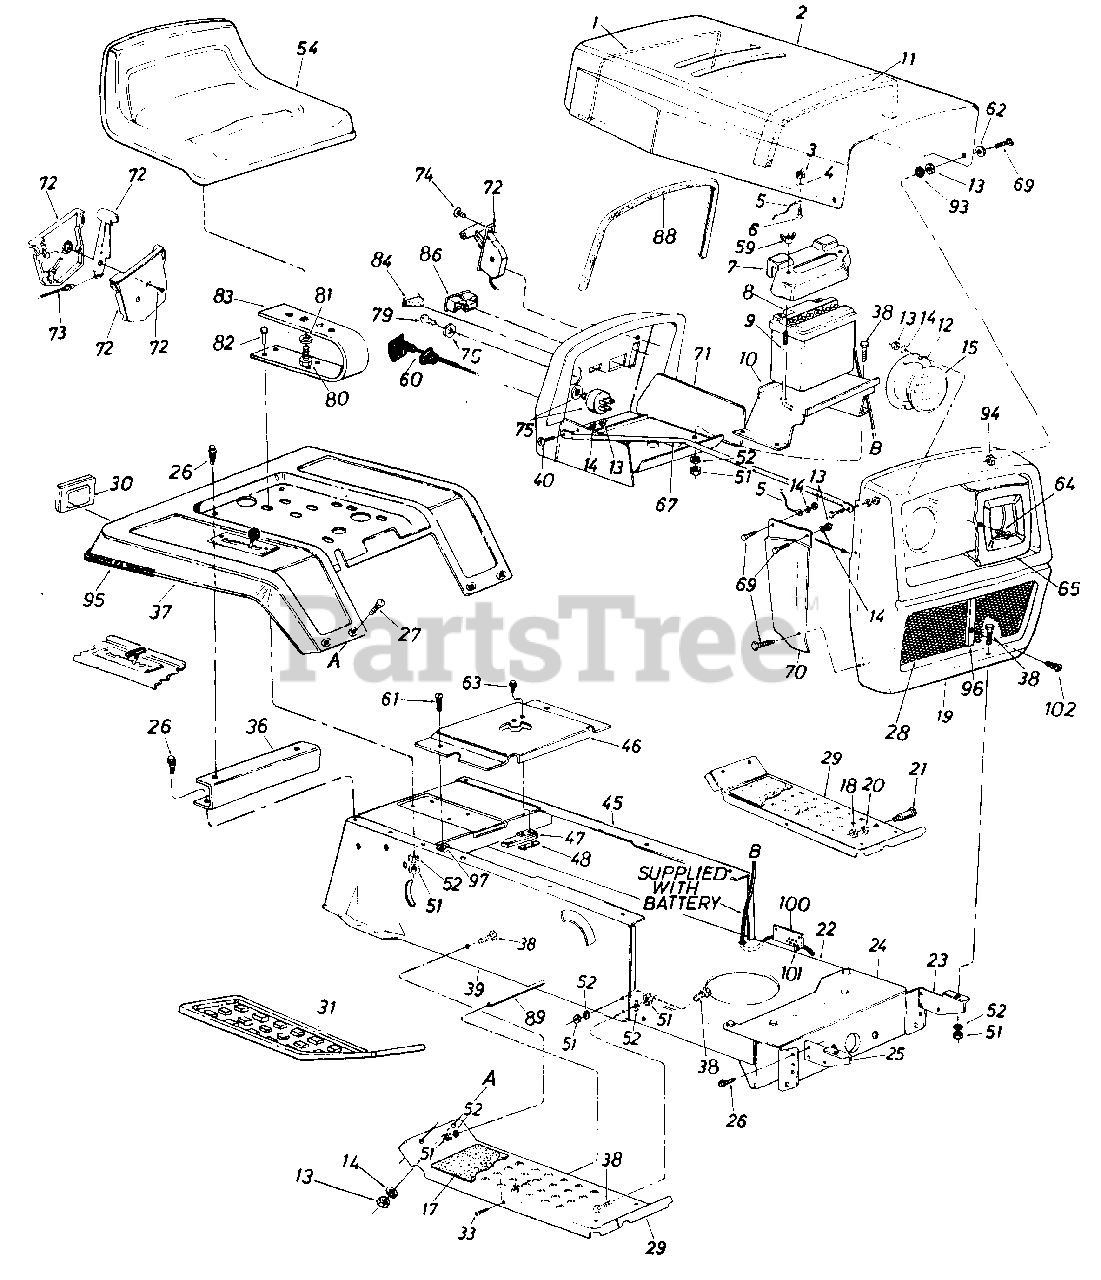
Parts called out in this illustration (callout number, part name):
2	Hood
3	Hex Sems Nut #10-24 Thd*
4	Push Mount Tie
5	Hood Stop 7" Lg.
6	Truss Hd. Scr. #10-24 x 1/2"*
7	Battery Cover
8	12 Volt Battery
9	Battery Hold Down Rod
10	Battery Bracket
11	PVC Foam Strip
12	Headlight Retainer
13	Hex Nut 1/4-20 Thd*
14	L-Wash. 1/4" I.D*
15	Headlight
17	Foot Pad
18	Hex Nut 3/8-16 Thd*
21	Shld. Bolt .50" Dia. x .84
22	Lower Frame
23	Grille Mount Brkt. L.H.
24	Front Pivot Brkt.
25	Grille Mount Brkt. R.H.
26	Hex Wash. Hd. AB-Tap Scr. 5/16 x .75" Lg.
27	Carr. Bolt 1/4-20 x 2.00" Lg*
29	Running Board
30	Reflector
31	Foot Pad
33	Truss Mach. Scr. 5/16-18 x .75" Lg*
36	Fender Mount Brace
37	Fender
38	Hex Bolt 5/16-18 x .75" Lg*
39	R.H. Side Frame
40	Hex Bolt '/4-20 x .62" Lg*
45	L.H. Side Frame
46	Shift Cover
47	Reverse Safety Switch
48	Insulator Nut Plate
51	Hex Nut 5/16-18 Thd*
52	L-Wash. 5/16" I.D*
54	Seat Ass'y.
59	Wing Nut 1/4-20 Thd. Plastic
60	Choke Control 44.0" Lg.
61	Truss Mach. Tap Scr. #10 x .50" Lg.
62	Fl-Wash. .281 I.D. x .73 O.D.
63	Hex Wash. Hd. AB-Tap Scr. #8 x .50
64	Truss Hd. Scr. #10-24 x .38" Lg.
69	Truss Hd. Scr. 1/4-20 x .75" Lg.
70	R.H. Grille Side Panel
71	Dash Panel Ass'y.
72	Throttle Control Box Ass'y.
73	Throttle Control Wire 35"
74	Truss Mach. AB-Tap Scr. #10 x .5" Lg.
75	Ignition Switch
79	Ignition Key
80	Hex Bolt 1/2-13 x 1.00" Lg. (Grade 5)
81	L-Wash. 1/2" I.D.
82	Hex Bolt 5/16-18 x 1.00" Lg.
83	Seat Spring 5.5" High
84	Light Switch
86	Ammeter
88	Molding Strip 27" Lg.
89	Running Board Rod
93	Rubber Wash. 1/2" I.D. x 1.0 O.D. x .25"
94	Hex Sems Ins. L-Nut 1/4-20 Thd.
95	Trim Strip 31.0" Lg.
96	Center Moulding
97	Speed Nut #10Z
100	Brake Cable Bracket
102	Truss Mach. Scr. #10-24 x .62" Lg.
